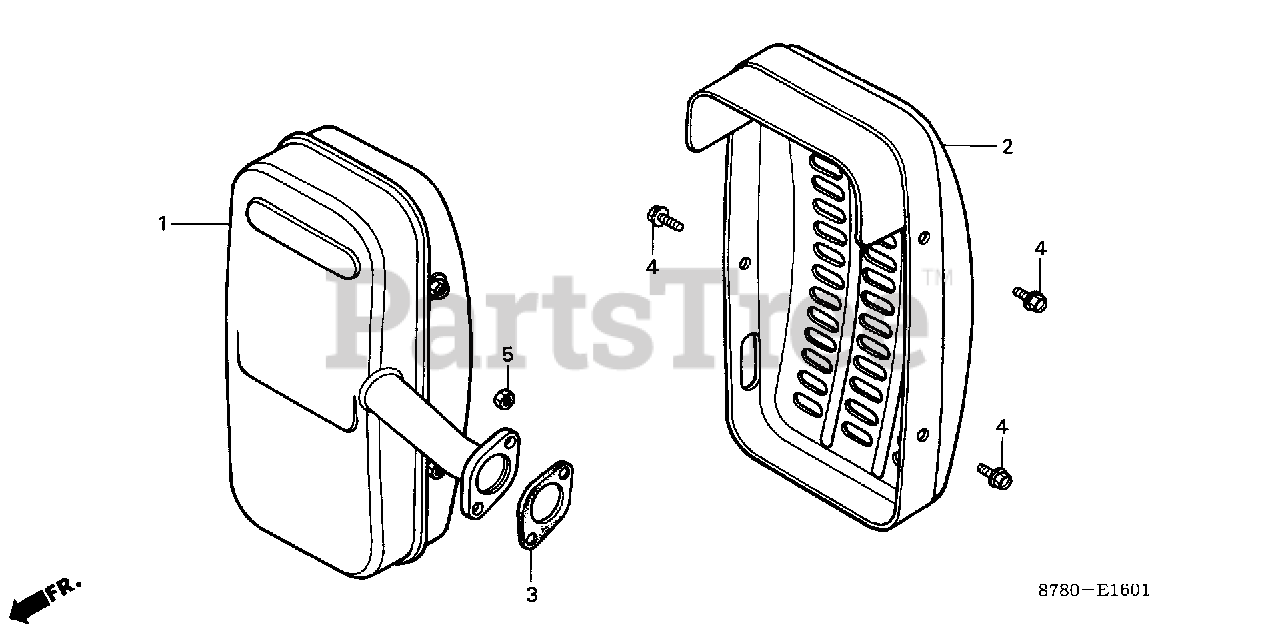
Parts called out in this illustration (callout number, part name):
1	MUFFLER (NOT AVAILABLE)
2	PROTECTOR, MUFFLER
3	GASKET, MUFFLER (NOT AVAILABLE)
4	BOLT, HEX. (6X6)
5	NUT, HEX. (6MM)
